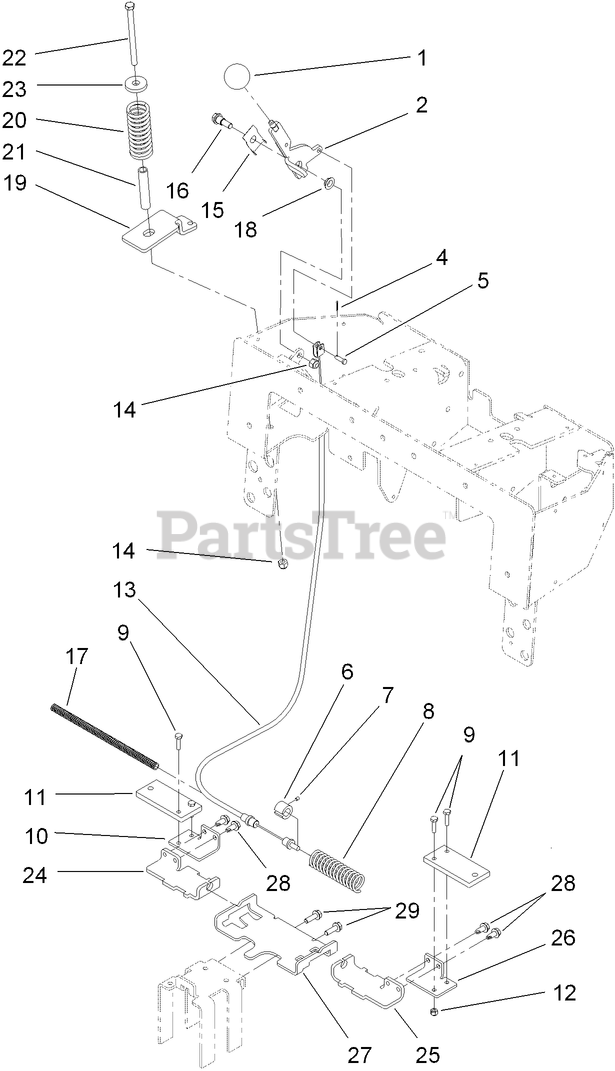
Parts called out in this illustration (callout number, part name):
2	HANDLE-BRAKE
4	PIN-COTTER
5	PIN-CLEVIS
6	Tube-Guide
7	SCREW-HSH
8	SPRING
9	SCREW-HH
10	BAR-LINK, BRAKE RH
11	PLATE-BRAKE
12	NUT-LOCK, NI
13	CABLE-BRAKE
14	NUT-LOCK, NI
15	SPRING-LEAF
16	BOLT-SHOULDER
17	TUBE-CONVOLUTED
18	BUSHING-FLANGE
19	BRACKET-CABLE, SPRING
20	SPRING-COMPRESSION
21	SPACER-SPRING
22	SCREW-HH
23	WASHER-HARDENED
24	BRACKET-MOUNTING, BRAKE RH
25	BRACKET-MOUNTING, BRAKE LH
26	BAR-LINK, BRAKE LH
27	SUPPORT-BAR, BRAKE
28	SCREW-HWH
29	SCREW-HHF
